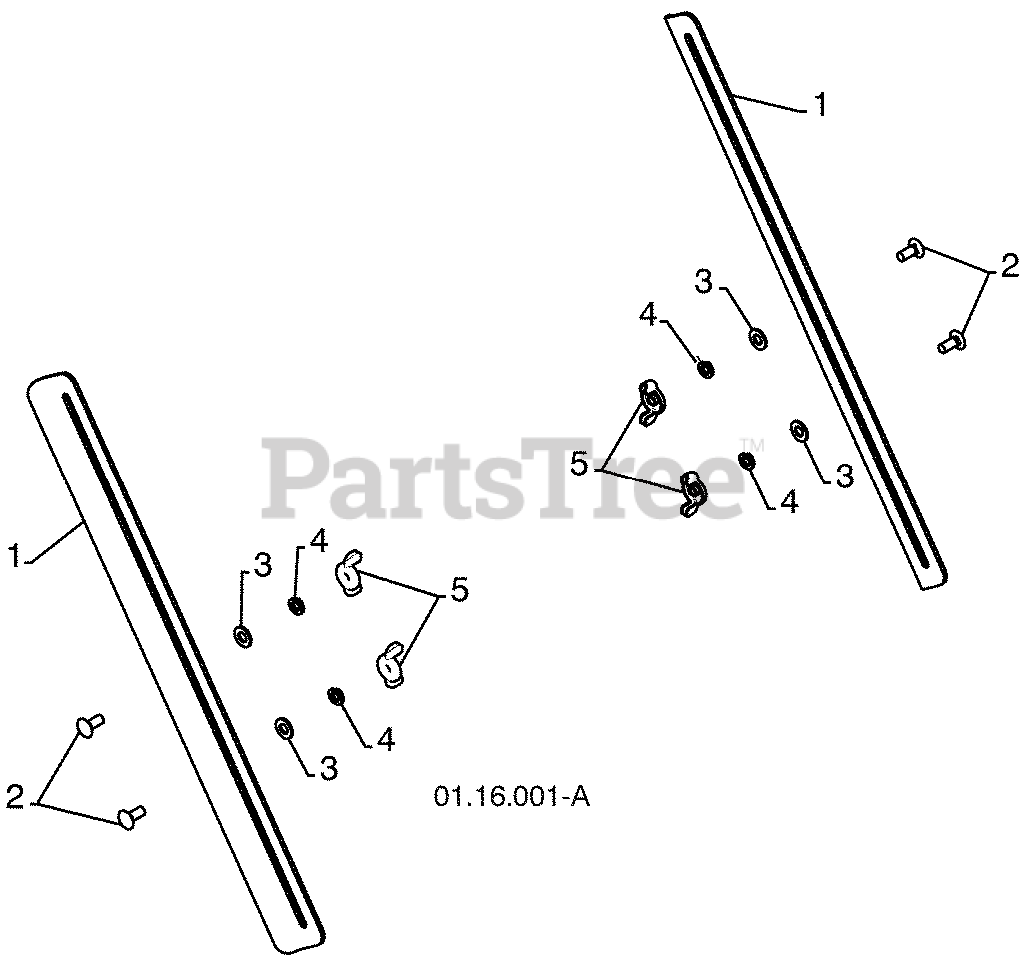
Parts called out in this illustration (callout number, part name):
1	DRIFT CUTTER BAR
2	BOLT
3	WASHER, NYLON FRICTION
4	WASHER.LOCK.HVY.HLCL.SPR.5/16
5	NUT WING PM
